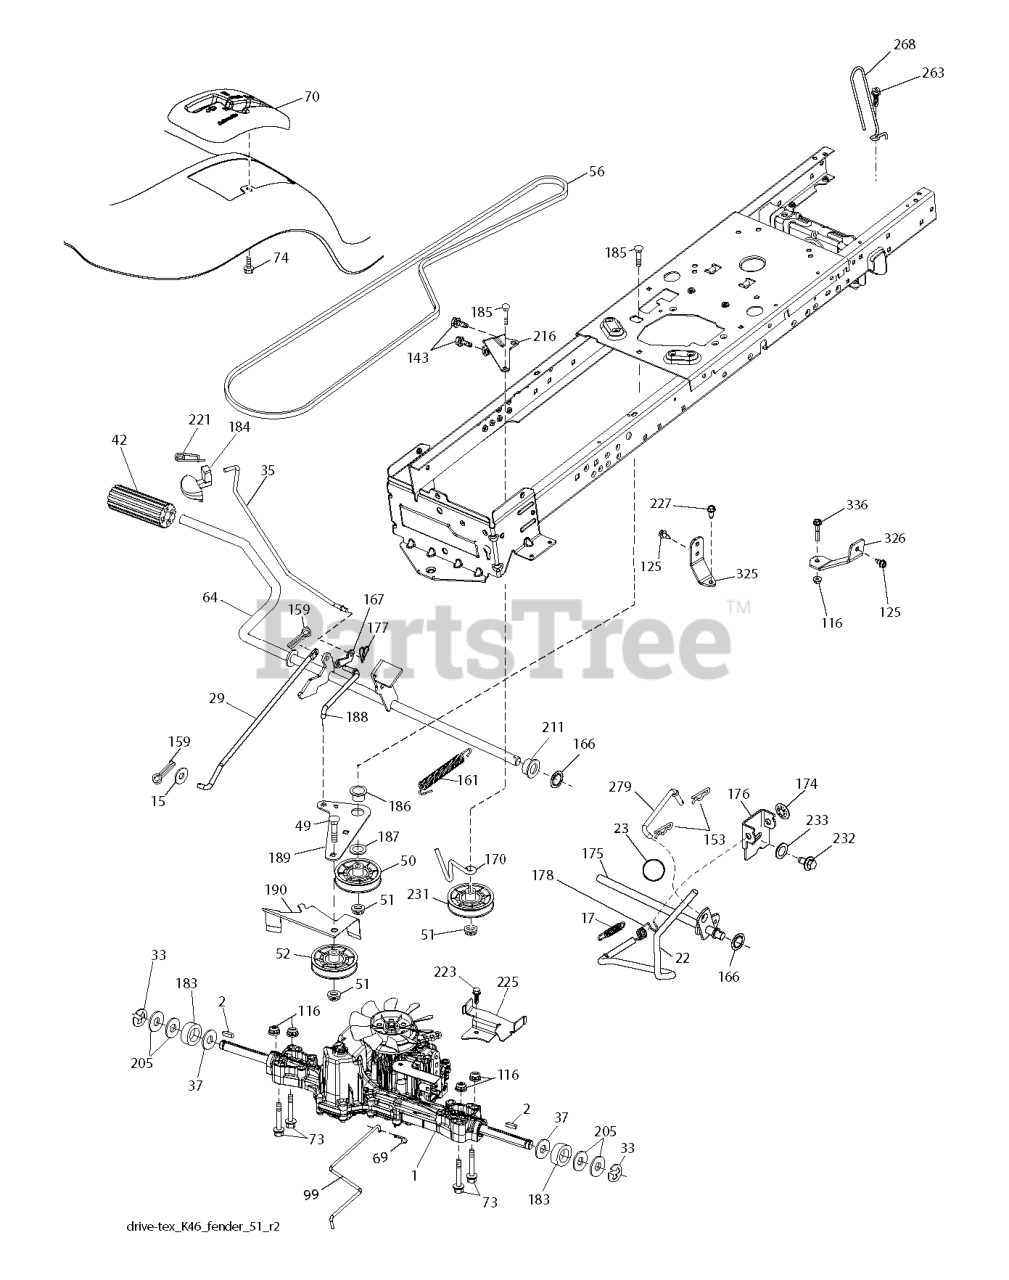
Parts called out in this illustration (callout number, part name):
2	SQUARE KEY
15	WASHER PLAIN WASHER 3/8 X 0.08
17	SPRING.BRAKE.K46.GREEN
22	ROD.SHIFT.FENDER.TLT.2006
23	KNOB.DELUXE.(PISTOL.GRIP).BLAC
29	ROD.BRAKE.K46
37	WASHER.HARDENED
42	PAD, FOOT PEDAL
50	IDLER.FLAT.910.OFFSET
51	NUT.HEX.FLANGE.3/8-16.LOCKNUT
52	IDLER.V-GROOVE.910.OFFSET
64	SHAFT.ASM.PEDAL.BRAKE.
69	HAIRPIN.SOFT.ZINC.059X1.125
70	CONSOLE.SHIFT.STL.HYD.TEX.GREY
99	ARM.PIVOTING.TCRD.GEN2.5.BAGGE
125	BOLT.HEX.HD.WASHER.5/16-18X.75
153	RETAINER M
161	SPRING, RETURN LT
166	NUT.PUSH.625
167	SERVICE KIT LATCH LATCH.BRAKE.
170	KEEPER.CENTER SPAN.1.688
174	NUT.PUSH.500.2006
175	SHAFT.ASM.SHFT.T2.TLT
176	ARM.CLEVIS.ROD.SHIFT
177	PIN COTTER;LOCKING;BOWTIE;1IN
178	SPRING.SHIFT.GT2006
183	SPACER AXLE
184	HANDLE.PARKNG BRK.PRED.LT.428
186	SPACER.RETAINER
188	LINK.CLUTCH.GROUND DRIVE.LONG
189	SERVICE KIT BELLCRANK
190	KEEPER.BELLCRANK.DRIVE
211	BUSHING.SHAFT.BRAKE.HAND
216	BRACKET.PULLEY.IDLER.W/TEX
221	RETAINER.SPRING.CLIP.H
225	SERVICE KIT KEEPER BELT KEEPER
231	IDLER.V-GROOVE.1.688.OFFSET
263	SCREW, 3/8-16X3/4
268	Mufflers
325	BRACKET TORQUE STRAP
326	BRACKET TORQUE STRAP
